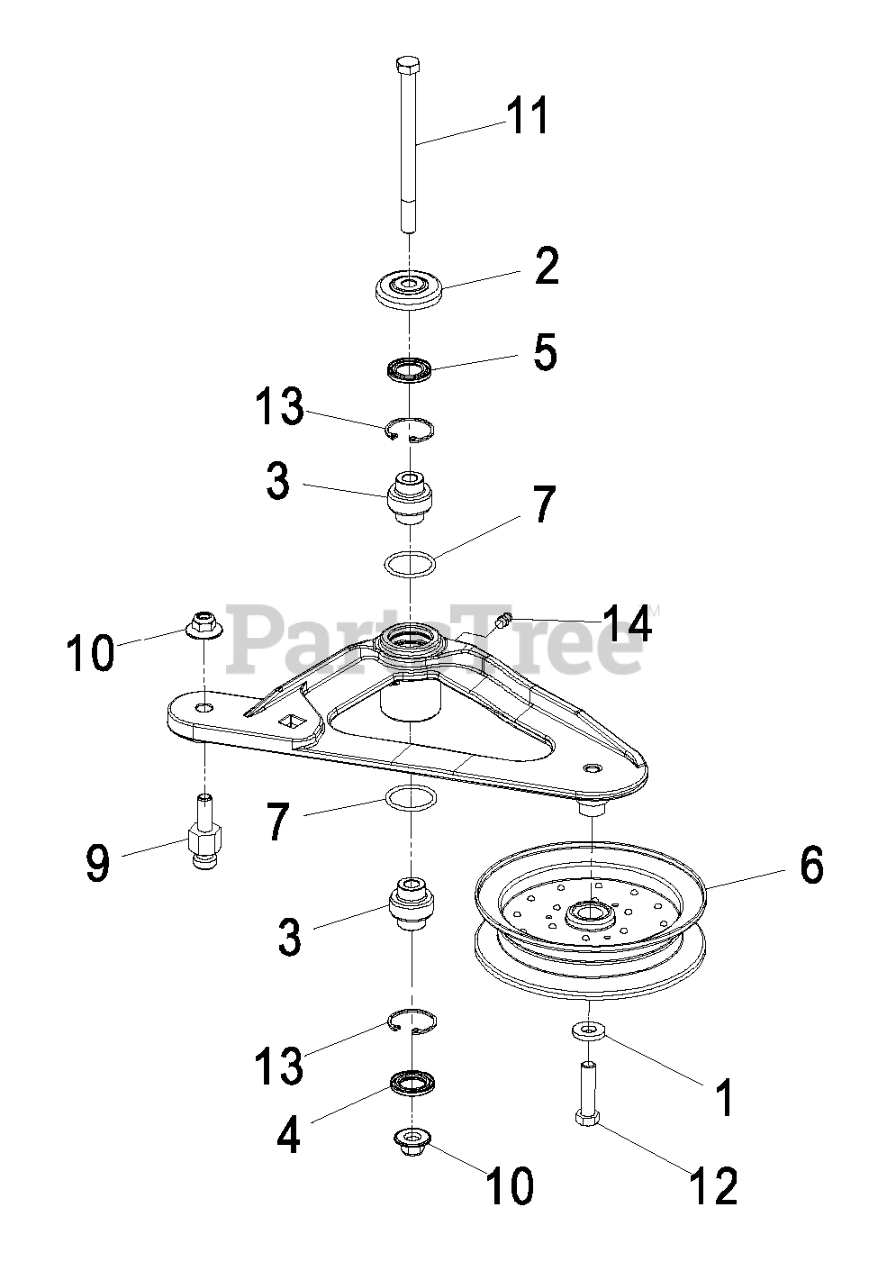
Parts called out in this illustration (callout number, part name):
2	GUARD-TOP
3	BEARING-SPHERICAL
4	SEAL-LIP, DOUBLE
5	SEAL-LIP, SINGLE
10	Nut-Nyloc 3/8-16 Flg
11	SCREW-SHOULDER, HH
12	SCREW-HH
13	RING-SNAP
14	FITTING-GREASE
